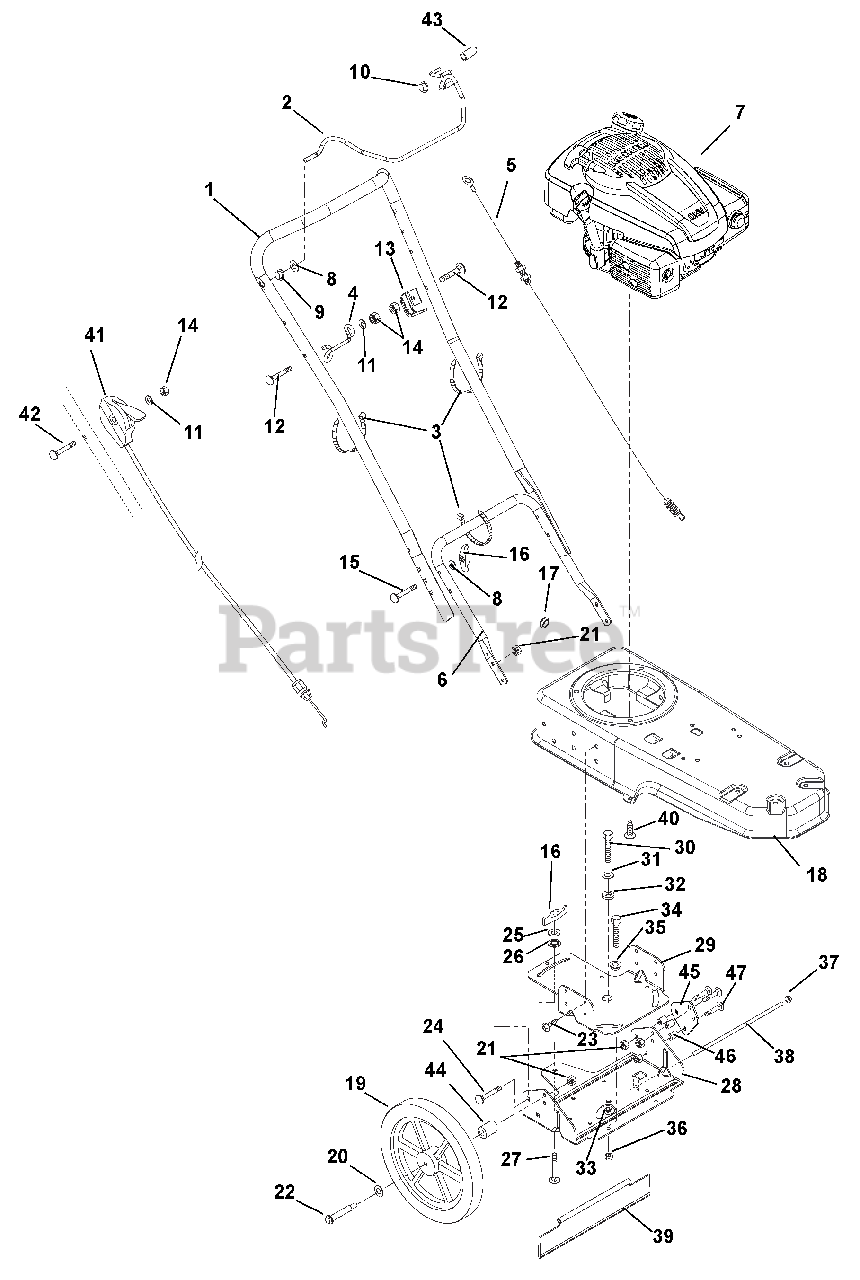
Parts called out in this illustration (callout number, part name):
1	HANDLEBAR - UPPER
2	BAIL SS LF
3	CABLE TIE LG 5-1/2
4	GUIDE - PULLCORD
5	CABLE - CONTROL
6	HANDLEBAR - LOWER
7	KOHLER XT8
8	@WSHR-FL-STL.344X.688X.065YWZC
9	BSHG-FLG .325X.444X.440X.560
10	PUSH NUT, .25
11	@WSHR-FL-STL.281X.62X.065 YWZC
12	BLT-RDHDXLSQNK.25-20X1.25 G5ZC
13	ANCHOR - CABLE
14	@NUT-LK-CTR .25-20 YWZC
15	BLT-RDHDSQNKFT .31-18X2.0 G5YZ
16	KNOB - WING .312-18 UNC
17	GROMMET .50 ID
18	FRAME - TRIMMER
19	WHEEL, 14" STRING TRIMMER
20	WSHR-FL-STL .52X.827X.062 YWZC
21	@NUT-LK-CTR .38-16 YWZC
22	BLT-SHLDR .38-16X2.50 HWH G5
23	@SCR-TAP .38-16X.75 HWH TR YWZ
24	@BLT-RDHDSQNK .38-16X.75 G5YZ
25	@WSHR-FL-STL.38X.875X.083 YWZC
26	NUT-PUSH .312
27	@BLT-RDHDSQNK .31-18X1.00 G5YZ
28	BRACKET - AXLE - SWIVEL
29	BASE - SWIVEL
30	@BLT-HEX .50-13X1.00 GR5 YWZC
31	@WSHR-FL-STL.563X1.38X.109YWZC
32	SPACER .531 X 1.00 X .225
33	@NUT-LK-CTR .50-13 YWZC
34	@BLT-HEX .31-18X1.00 GR5 YWZC
35	BSHG-FLG .32X.500X.344X.880
36	@NUT-LK-CTR .31-18 YWZC
37	NUT-PUSH .312 DIA. PAL
39	GUARD - REAR - SWIVEL
40	@SCR-TAP .38-16X1.00 HWH TR YZ
41	CABLE, BRIGGS TRIMMER THROTTLE
42	BLT-RDHDXLSQNK .25-20X2.0 G5YZ
43	CAP, VINYL, .25 ID
44	BSHG-SLV .377X.624X.235
45	BRKT,TRIMMER WHEEL
46	BSHG-SLV .469 X .750 X .430
47	@BLT-RHDSSQNK .38-16X1.50 G5YZ
